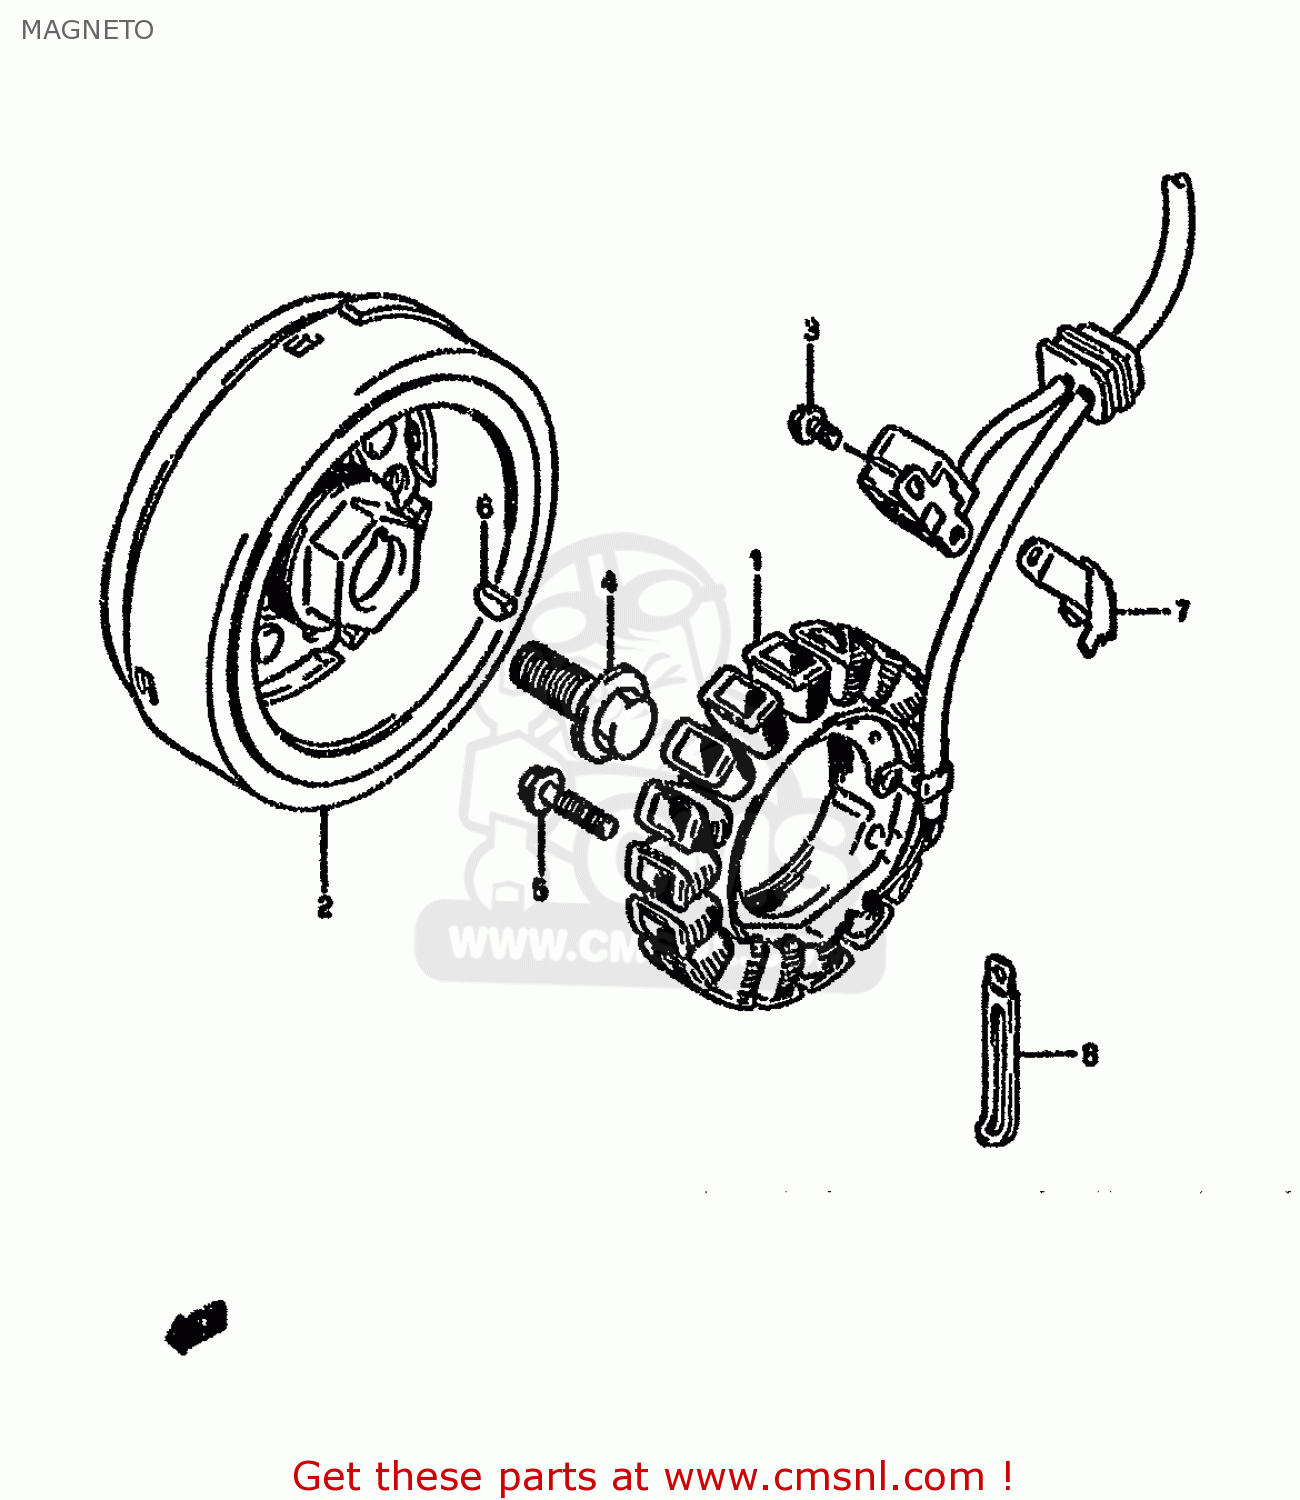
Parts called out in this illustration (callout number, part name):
1	STARTER ASSY
2	ROTOR
3	BOLT
4	BOLT(14X43)
5	BOLT
6	KEY
7	CLAMP,MAGNETO LEAD WIRE
8	CLAMP
